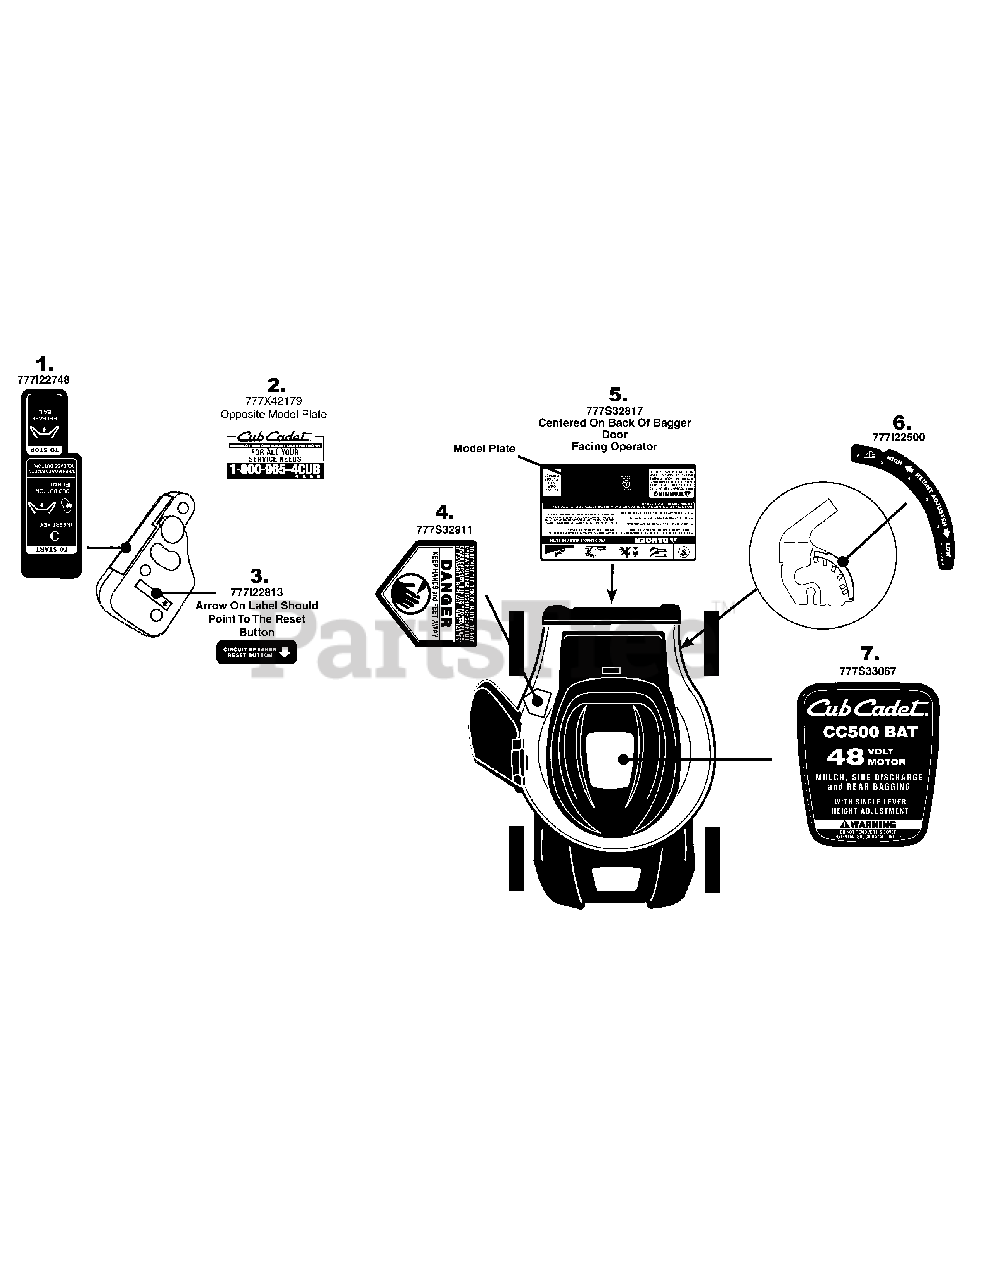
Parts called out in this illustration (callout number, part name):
1	LABEL-SWITCH START
2	LABEL-CUB HOTLINE
3	LABEL-BREAKER RESET UL ELC/BAT
4	LABEL-CUT FINGER UL ELEC/BATT
5	LABEL-REAR SAFETY
6	LABEL:MOWER HGT ADJ
7	LABEL-CC500 BAT
